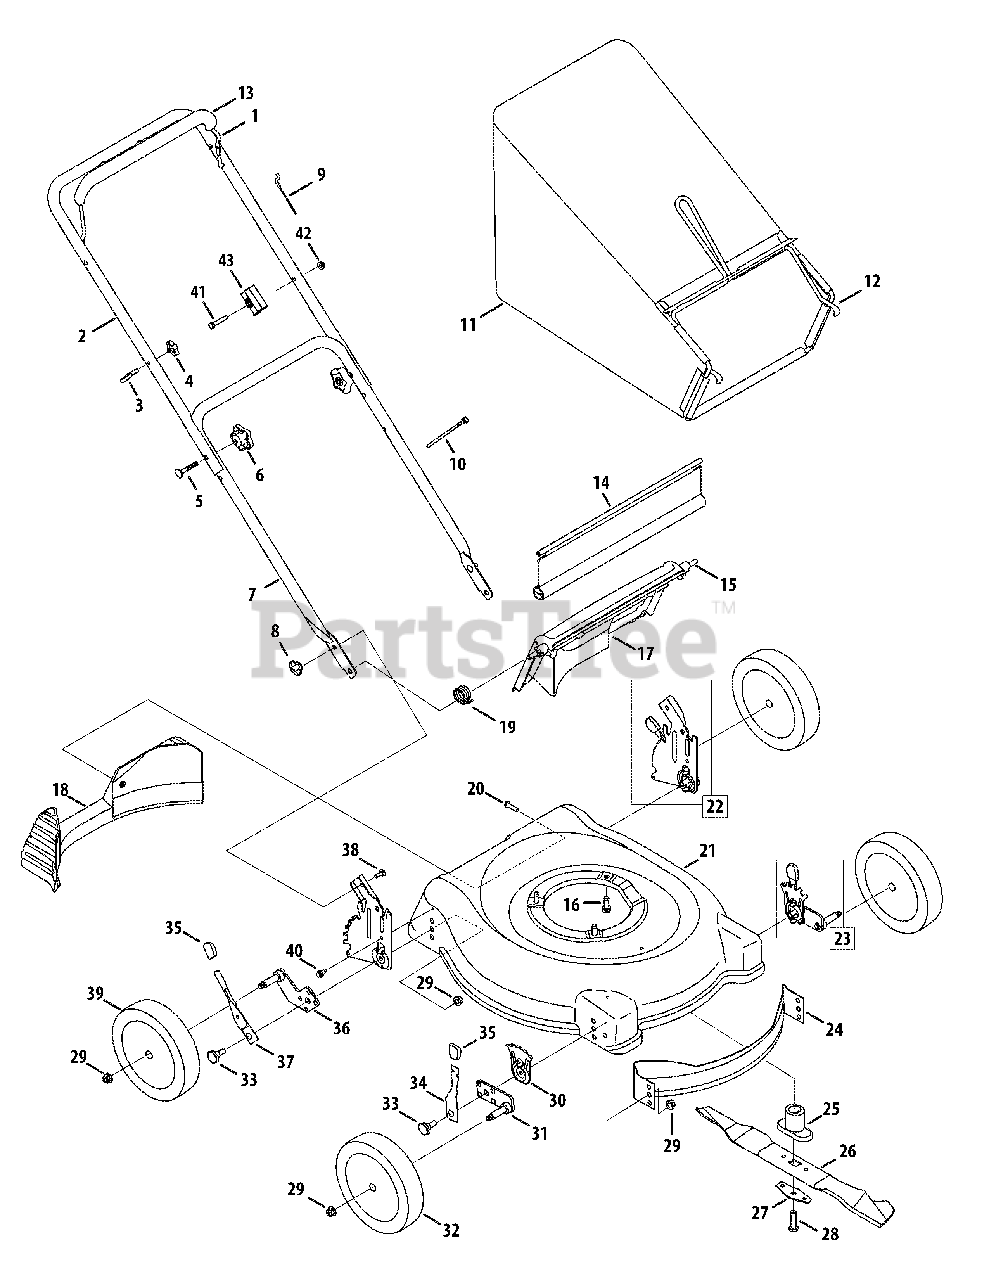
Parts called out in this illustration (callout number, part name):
1	Blade Control
2	Upper Handle
3	Rope Guide
4	Wing Nut, 1/4-20
5	Carriage Bolt, 5/16-18 x 2
6	Hand Star Knob
7	Lower Handle
8	Wing Nut, 1/4-20
9	Control Cable - 37.25"- Briggs & Stratton & Honda
9	Control Cable - 37.25" - Kohler
10	Cable Tie
11	Grass Bag
12	Grass Bag Frame
13	Bail Cover
14	Trailshield
15	Rear Door Pivot Rod
16	TT Screw, 3/8-16 x 1
17	Rear Discharge Door
18	Rear Baffle
19	Torsion Spring RH
20	Screw, 1/4-15 x 1.00
21	Deck 21 inch - Red
21	Deck 21 inch - Green
22	Handle Bracket Assy - RH
22	Handle Bracket Assy - LH
23	Height. Adj. Assy Frt - LH (8" Wheel)
23	Height Adj. Assy. Frt - RH (8" Wheel)
23	Height Adj. Assy. Frt - LH (7" Wheel)
23	Height Adj. Assy. Frt - RH (7" Wheel)
23	Height Adj. Assy. Frt . LH
23	Height Adj. Assy. Frt . RH
24	Front Baffle
25	Blade Adapter
26	Standard Blade
26	Mulch Blade
27	Blade Bell Support
28	Screw, 3/8-24 x 2.50
29	Flange Lock Nut, 3/8-16
30	Height Adjustment Plate
31	Pivot Arm Assy LH (7" wheel)
31	Pivot Arm Assy RH (7" wheel)
31	Pivot Arm Assy RH (8" wheel)
31	Pivot Arm Assy LH (8" wheel)
31	Pivot Arm Assy LH
31	Pivot Arm Assy RH
32	Wheel, 7 x 1.8
33	Shoulder Screw
34	Spring Lever
35	Height Adjustment Knob
36	Pivot Arm Assembly - RH
36	Pivot Arm Assembly - LH
37	Spring Lever
38	Carriage Bolt, 1/4-20
39	Wheel, 8 x 1.8
40	Screw, 1/4-20 x .625
41	Screw, 1/4-20 x 1.50
42	Nut, Flglk, 1/4-20
43	Cable Mount
